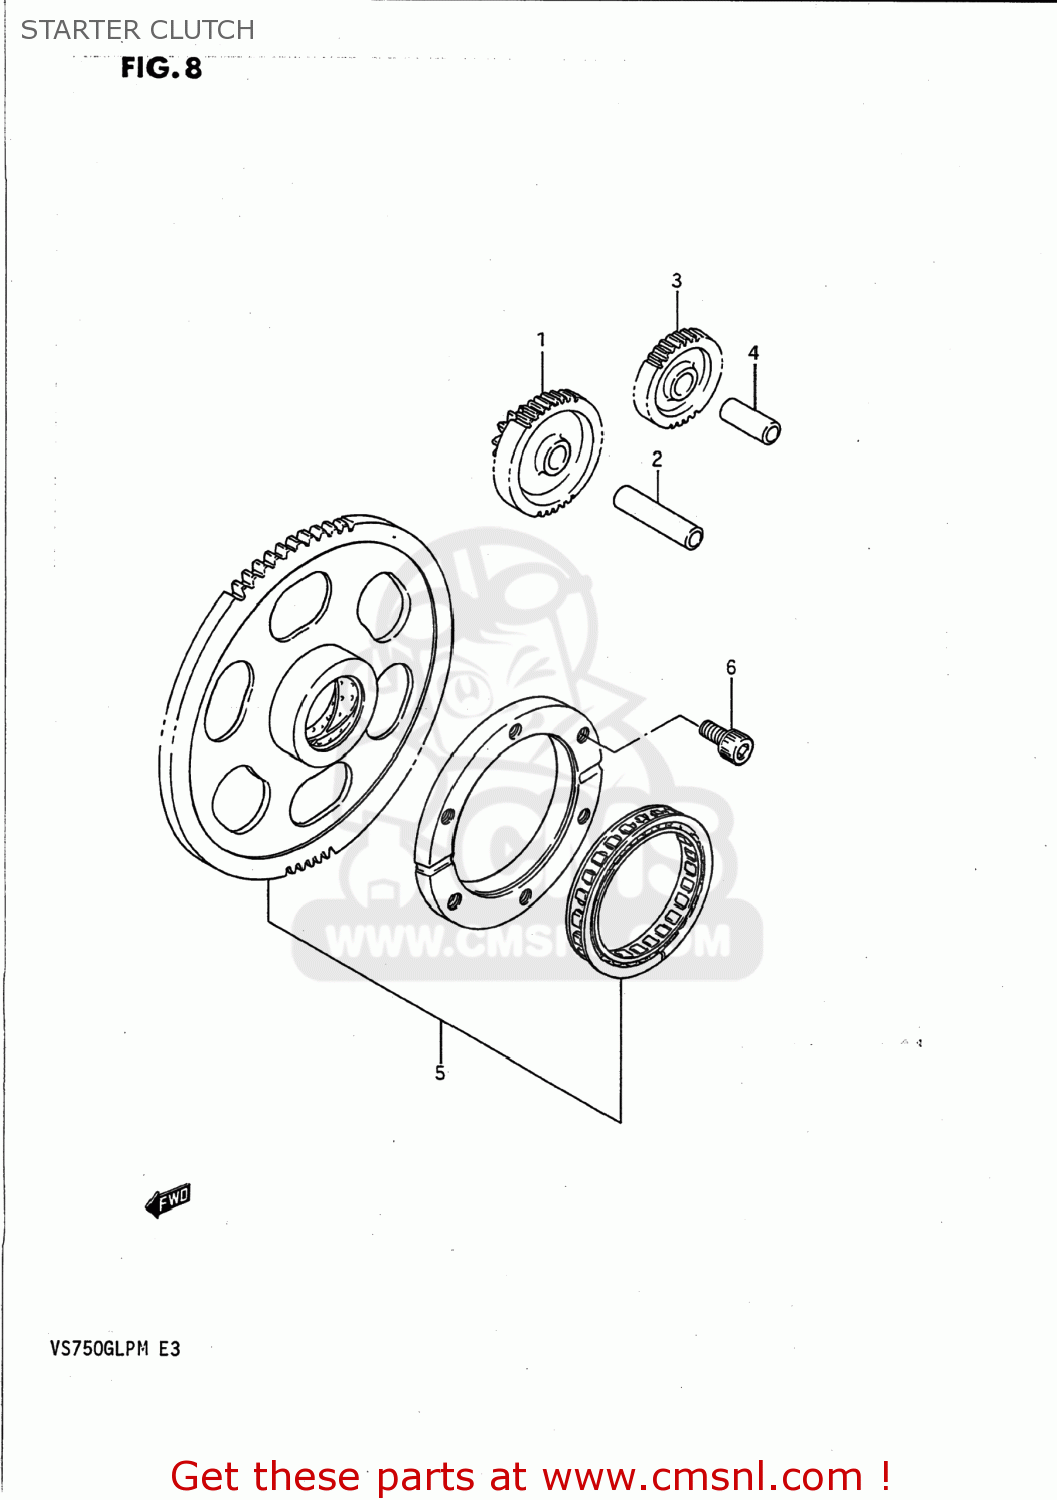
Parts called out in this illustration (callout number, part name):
1	GEAR,STARTER IDLE NO.1
2	PIN
3	GEAR,STARTER IDLE NO.2
4	PIN
5	CLUTCH SET,STARTER
6	BOLT
